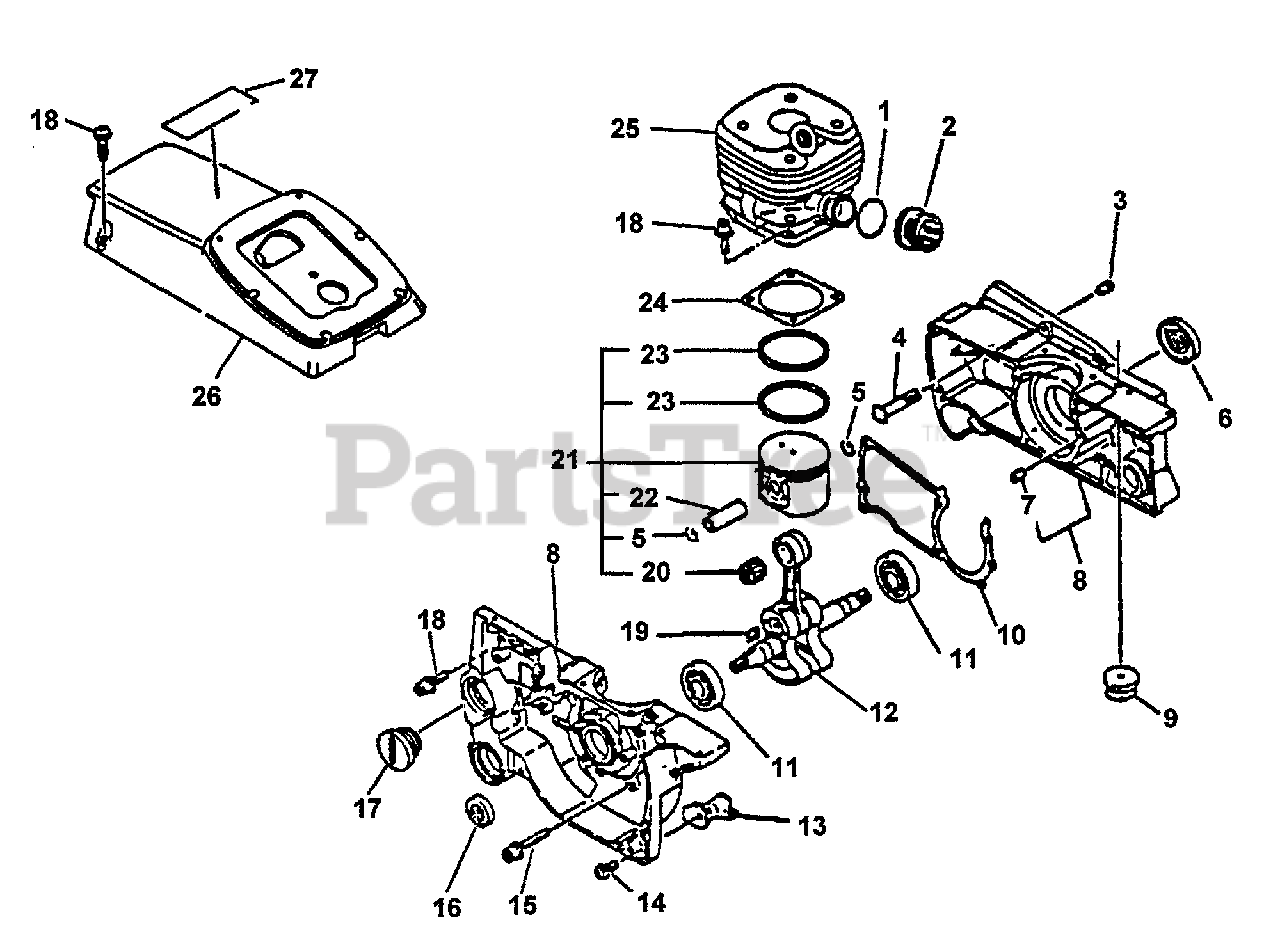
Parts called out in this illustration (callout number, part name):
2	ADAPTOR, INTAKE
3	VENT ASSY
5	RING, SNAP
6	SEAL, OIL
7	PIN, LOCATING 5×10
8	CRANKCASE KIT
10	GASKET, CRANKCASE
11	BEARING, BALL 6202
12	CRANKSHAFT ASSY
14	SCREW 5×14
15	BOLT M5×35
16	SEAL, OIL
17	PLUG
18	BOLT 5×20
19	KEY, WOODRUFF
20	BEARING, NEEDLE
21	PISTON KIT
22	PIN, PISTON
23	RING, PISTON
24	GASKET, CYLINDER
25	CYLINDER KIT
26	COVER, ENGINE
27	LABEL, CAUTION
